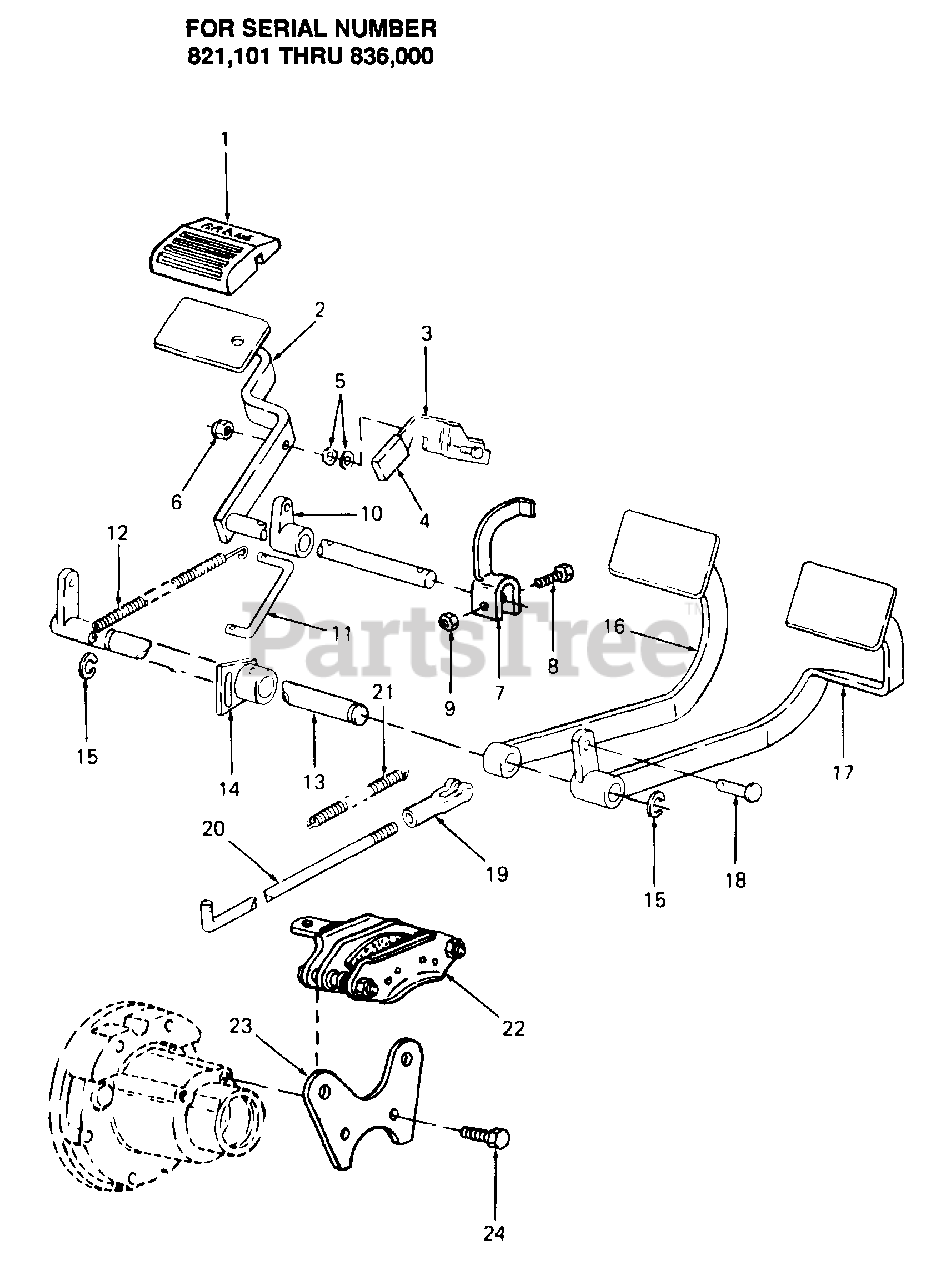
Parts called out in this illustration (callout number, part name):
1	Pad, Brake Pedal
5	Washer, Wave, 1/4 Dia
6	Nut, Hex Insert Lock, 1/4-20
9	Nut, Hex Center Lock, 1/4-20
11	Rod, Center Brake
12	Spring, Extension, .50 OD X 7.32 Lg
13	Shaft Assy, Brake
14	Arm Assy, Parking Brake Plate
15	Ring, Retaining
18	Pin, Clevis, 3/8 Dia X 1.56 Lg
19	Clevis, Adjustment
20	Rod, Brake
21	Spring, Extension, .66 OD X 3.3 Lg
22	Kit, Brake Caliper
23	Bracket, Brake Mounting
24	Bolt, Hex Patch, 5/16-18 X 1.0 Lg GR5
